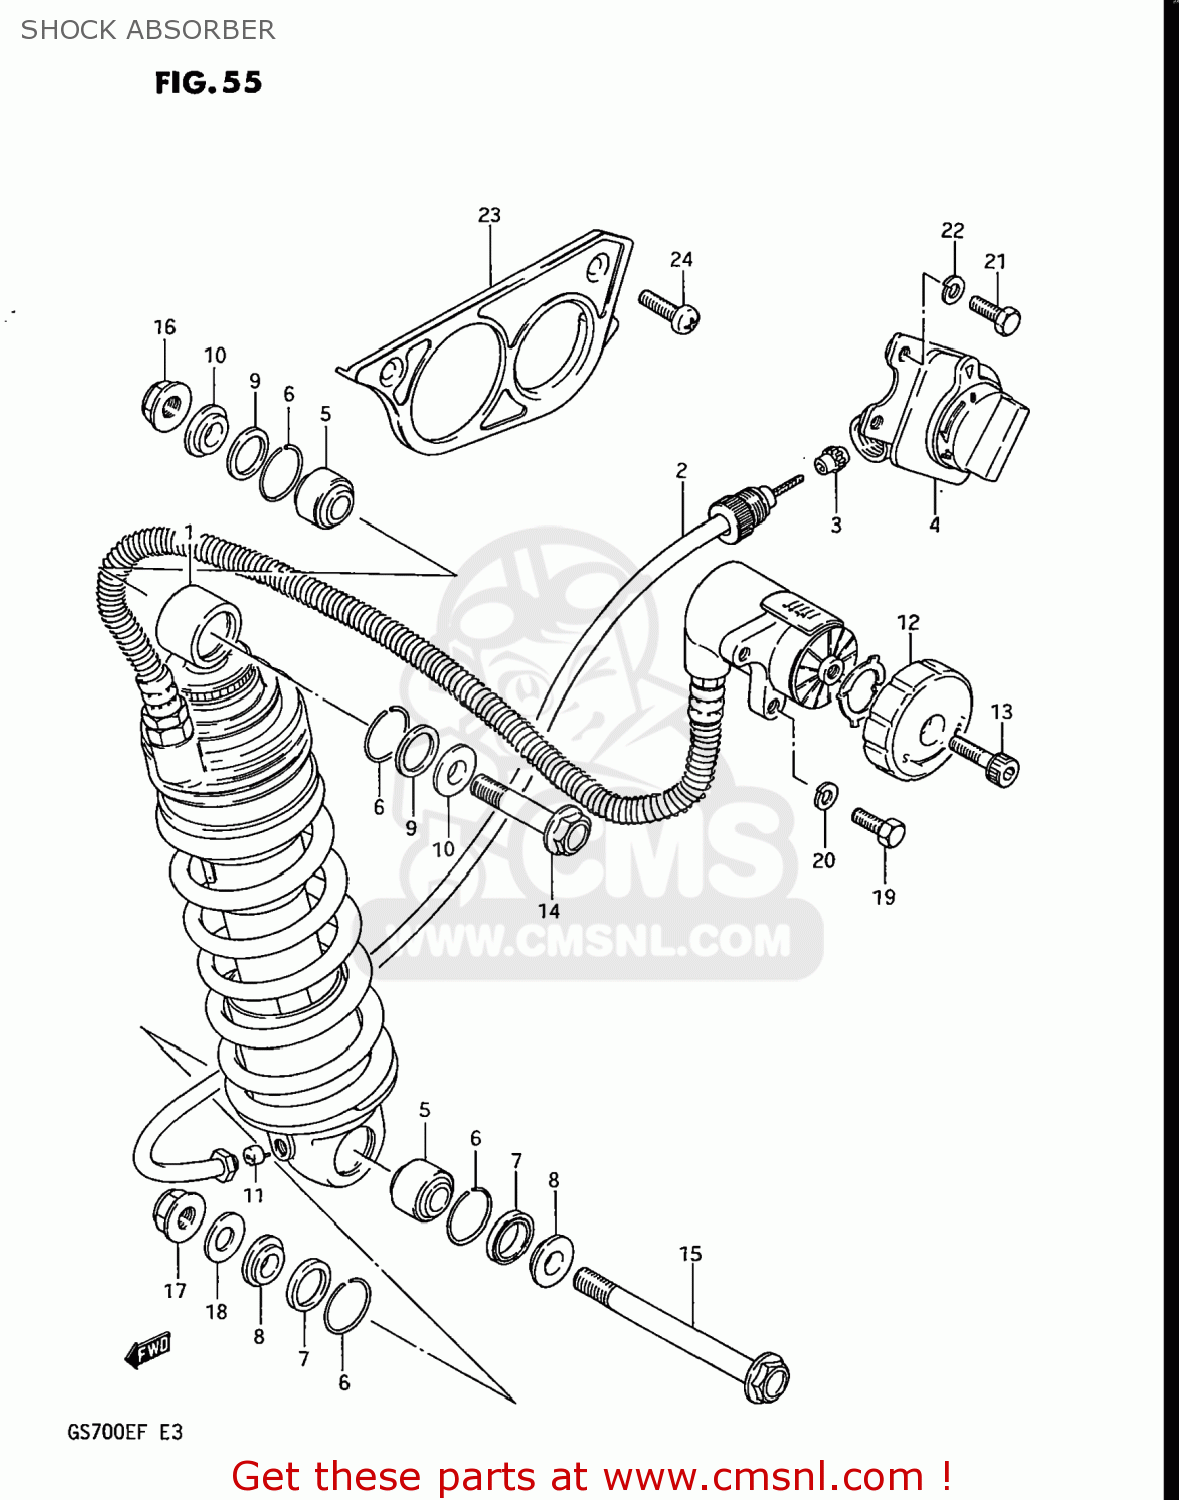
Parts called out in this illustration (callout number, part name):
1	ABSORBER,REAR SHOCK
2	CABLE,CONTROL
3	GEAR
4	ADJUSTER
5	BEARING,REAR SHOCK ABSORBER
6	RING
7	DUST SEAL
8	SPACER
9	SEAL,DUST
10	COLLAR
11	CAM,DAMPER ADJUSTER
12	PLATE,LEVELING
13	BOLT
14	BOLT(10X50)
15	BOLT(10X115)
16	NUT
17	NUT
18	WASHER
19	BOLT 6X16
20	WASHER,LOCK
21	BOLT 6X16
22	WASHER,LOCK
23	COVER,REAR SHOCK ABSORBER ADJUSTER
24	SCREW
